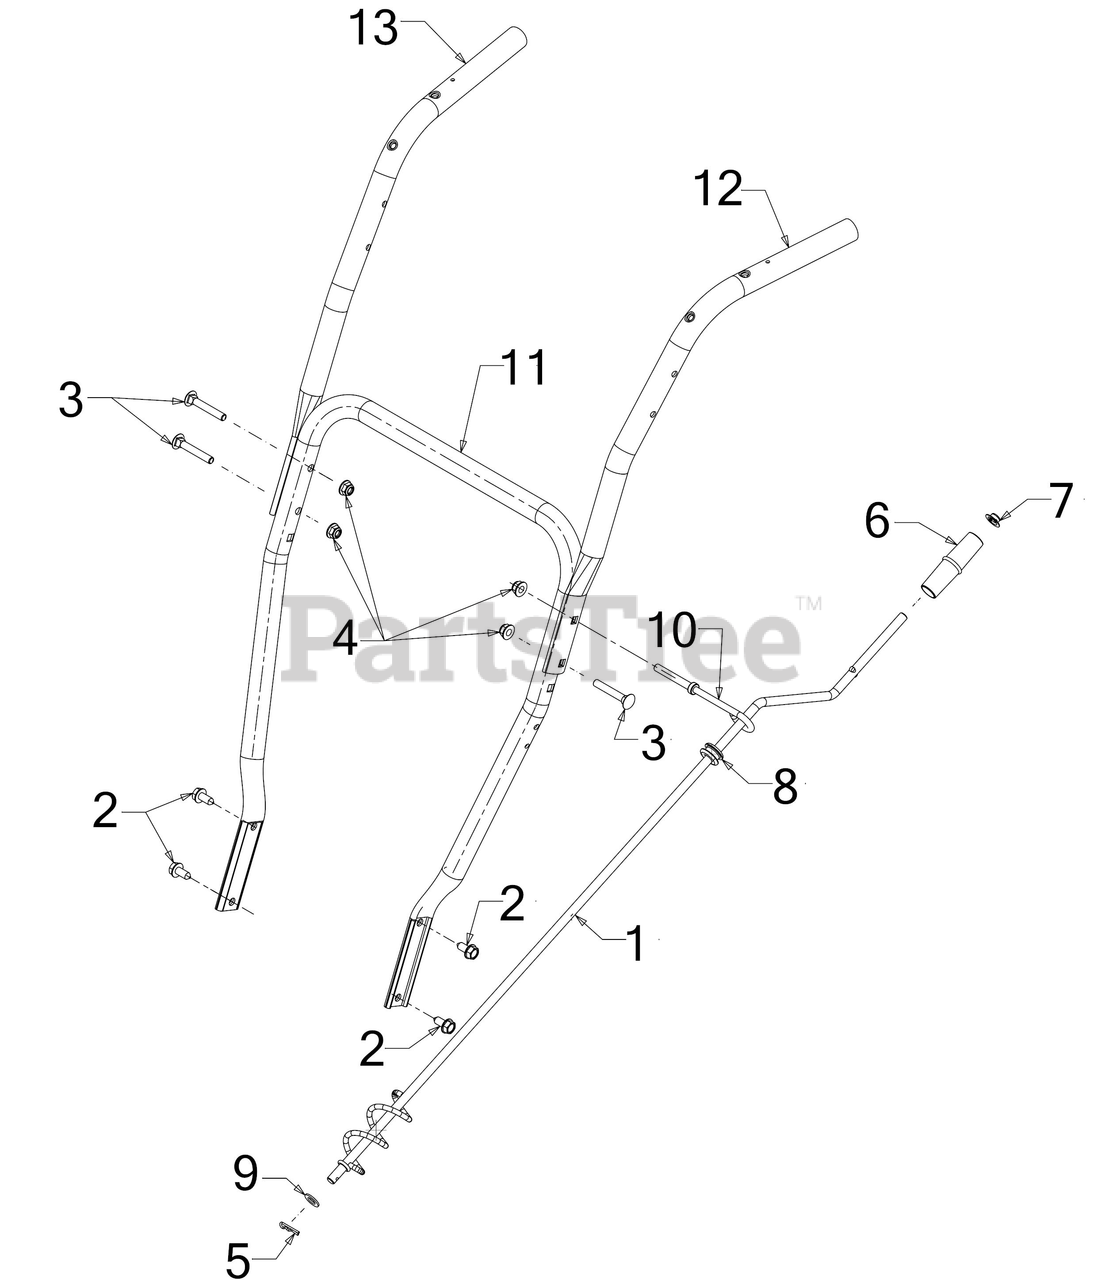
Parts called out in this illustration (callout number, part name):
1	CHUTE CRANK ASSEMBLY
2	SCREW 5/16-18 x .750
3	CARRIAGE BOLT 5/16-18 x 2.00 GR5
4	FLANGE LOCK NUT 5/16-18
5	COTTER PIN .072 DIA
6	CHUTE CRANK KNOB
7	PUSH NUT
9	FLAT WASHER
10	CHUTE CRANK EYEBOLT
